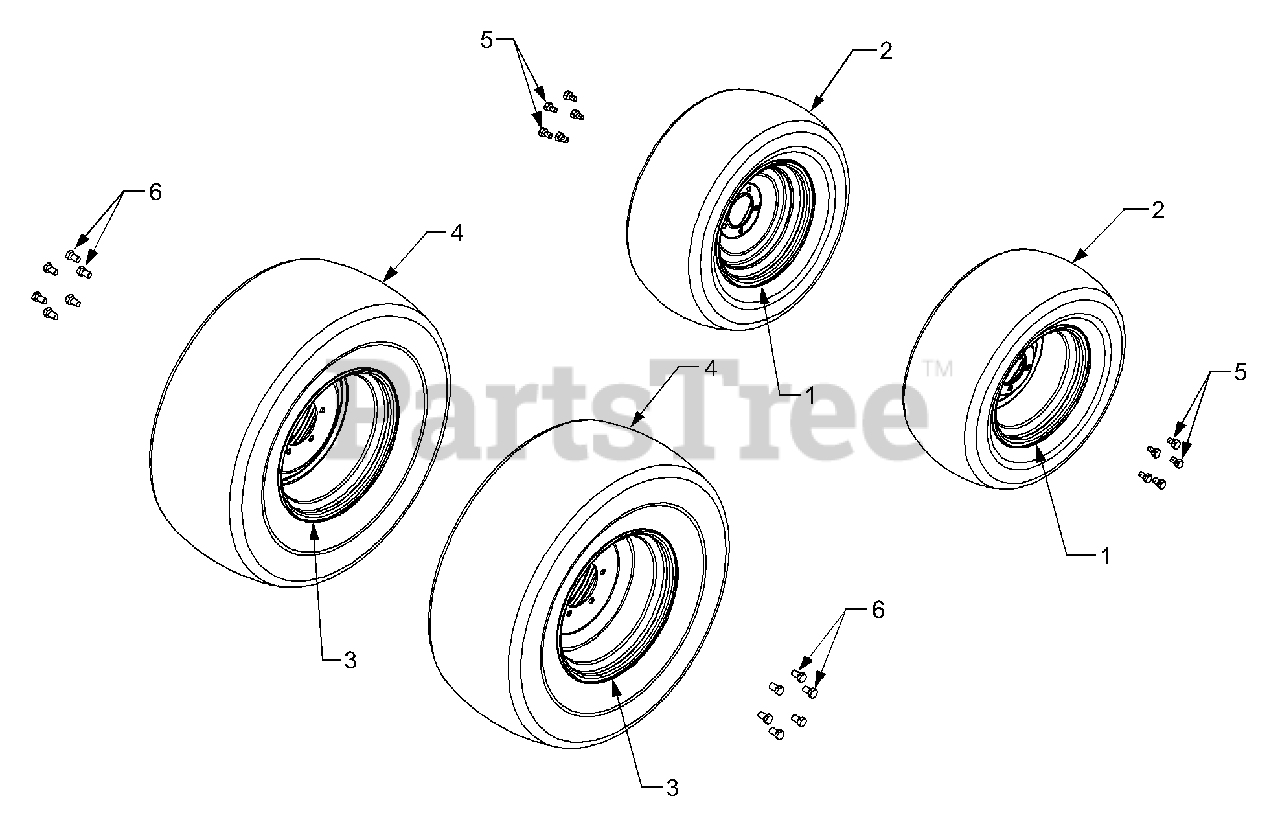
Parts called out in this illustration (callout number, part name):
1	Rim, TURF Tire - Front
2	Tire, Turf
3	Rim, TURF Tire - Rear
4	Tire, Turf
5	Screw, Lug, M12
6	Bolt, Lug, M14 x 1.5 x 20
